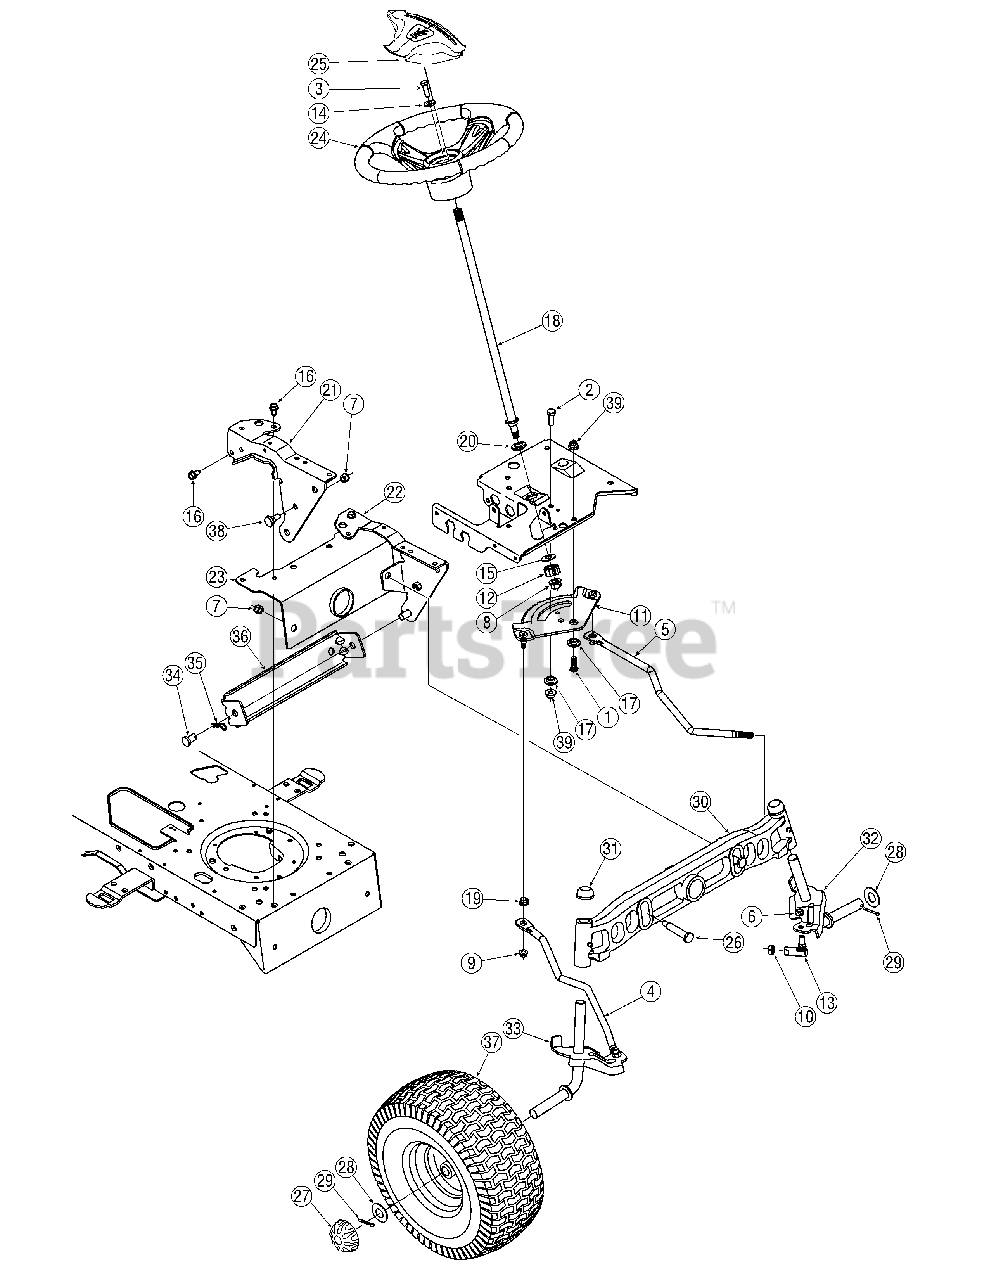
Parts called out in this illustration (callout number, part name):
1	Hex Screw, 3/8-16, 1.00, Gr5
2	Hex Screw, 3/8-16, 1.00, Gr5
3	Hex Screw, 5/16-18, 1.00, Gr5
4	Link, Drag, RH
5	Link, Drag, LH
6	Nut, Hex Lock, 3/8-24
7	Nut, Flange Lock, 3/8-16, Grf, Nylon
8	Nut, Flange Lock, 7/16-20
9	Nut, Flange Lock, 5/16-18, Gr5
10	Nut, Jam, 7/16-20, Gr2
11	Gear, Steering, 11/90 Ratio
12	Gear, Pinion, Steering
13	Ball Joint, 7/16-20, Lock
14	Washer, Flat,.406 x.875 x.105
15	Washer, Flat,.51 x 1.12 x.06
16	Screw, 5/16-18, 0.750
17	Spacer, Shoulder,.38 x 1.00 x.31
18	Shaft, Steering,.625 OD x 24.25 Lg
19	Plastic Bushing.380 ID
20	Hex Flange Bearing 5/8 PM
24	Steering Wheel, 13.25
25	Steering Wheel Cover
26	Shoulder Screw,.5 x 2.2, 3/8-16
27	Deluxe Hub Cap
28	Flat Washer,.78 x 1.589 x.06
29	Cotter Pin, 5/32 x 1.25
30	Cast Iron Pivot Bar
32	LH Axle Assembly,.750
33	RH Axle Assembly,.750
34	Pin, Clevis,.50 x.78
35	Cotter Pin, Internal,.080 x 1.5625
38	Screw, Shoulder,.498 x.340, 3/8-16
39	Flange Lock Nut, 3/8-16
